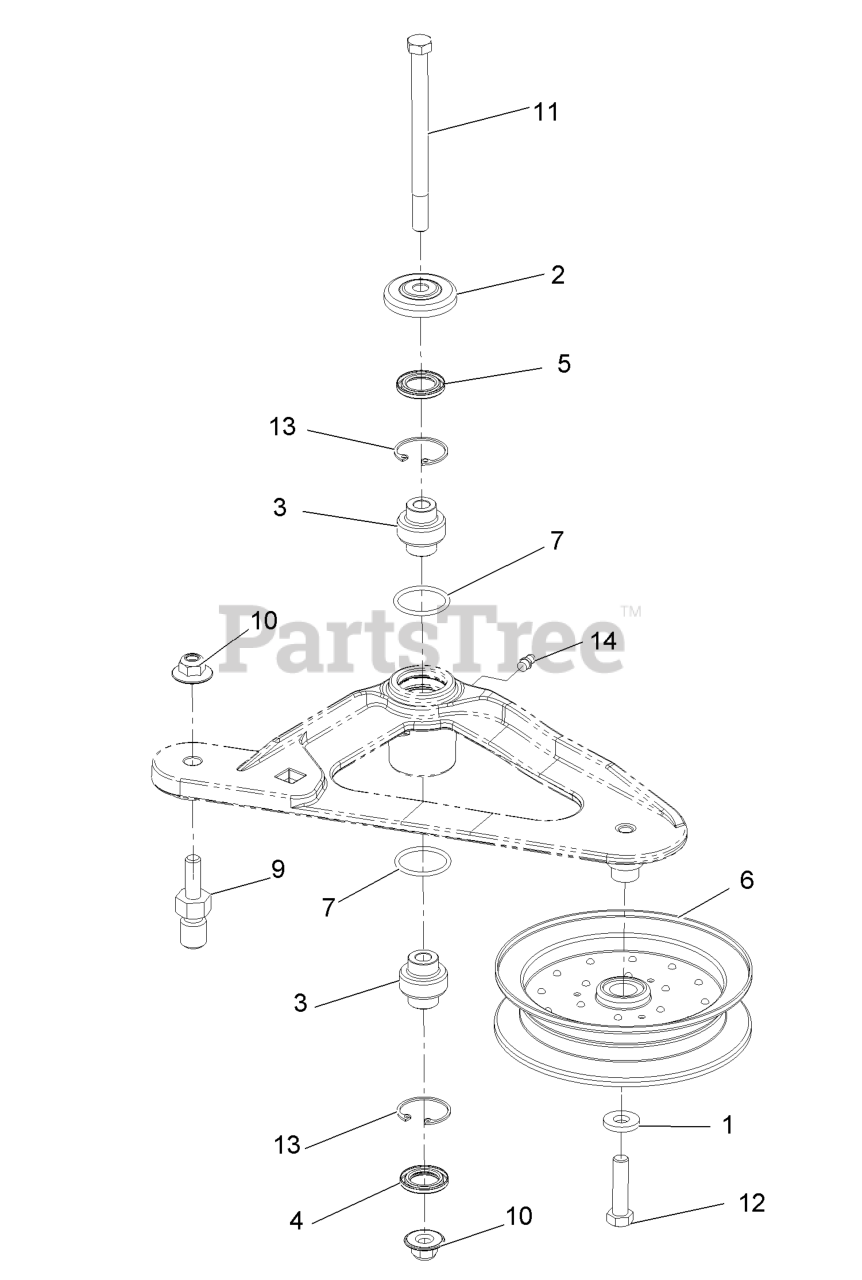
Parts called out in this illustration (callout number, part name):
2	GUARD-TOP
3	BEARING-SPHERICAL
4	SEAL-LIP, DOUBLE
5	SEAL-LIP, SINGLE
10	Nut-Nyloc 3/8-16 Flg
11	SCREW-SHOULDER, HH
12	SCREW-HH
13	RING-SNAP
14	FITTING-GREASE
